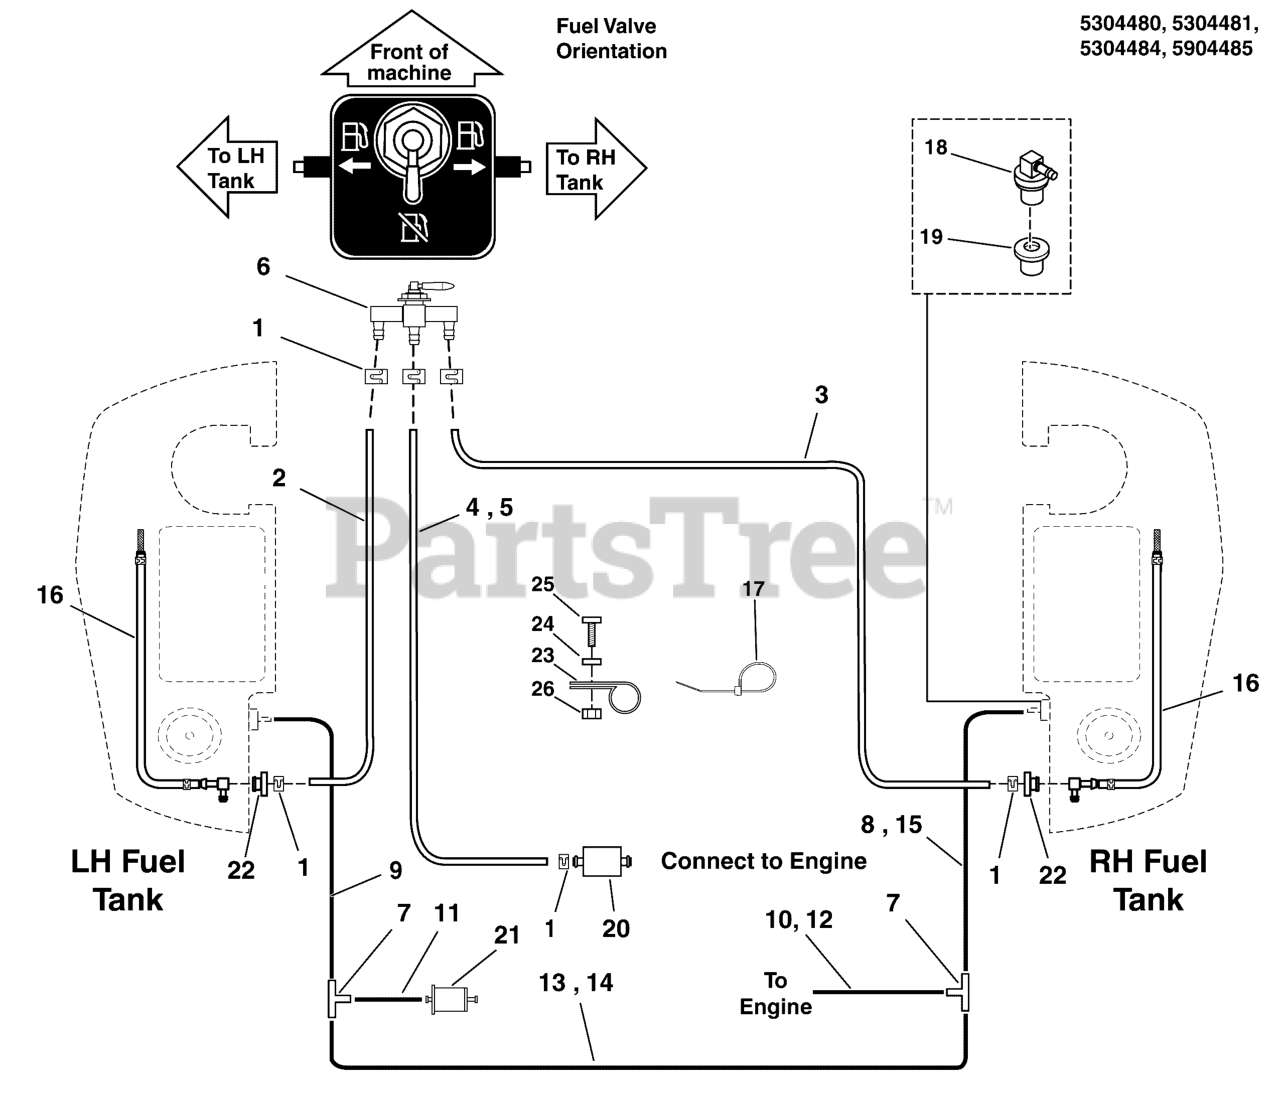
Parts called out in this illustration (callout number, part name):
1	CLAMP, HOSE, EXTERNAL, 1/2 - RED
2	HOSE, 1/4" FUEL, 14.50"
3	HOSE, 1/4" FUEL, 49.00"
4	HOSE, 1/4" FUEL, 22.00"
5	HOSE, 1/4" FUEL, 11.00"
6	VALVE, FUEL SHUT-OFF, 11772
7	FITTING, 3/16" TEE, BARB TYPE, HDPE
8	HOSE, VAPOR, 5MM ID, 41.00 LG
9	HOSE, VAPOR, 5MM ID, 26.00 LG
10	HOSE, VAPOR, 5MM ID, 31.50 LG
11	HOSE, VAPOR, 5MM ID, 2.00 LG
12	HOSE, VAPOR, 5MM ID, 11.00 LG
13	HOSE, VAPOR, 5MM ID, 2.00 LG
14	HOSE, VAPOR, 5MM ID, 13.50 LG
15	HOSE, VAPOR, 5MM ID, 28.00 LG
16	HOSE ASSEMBLY (SV)
17	TIE,SELF-LOCKING, 6"
18	REMOTE VENT ASSEMBLY
19	GROMMET (SV)
20	FUEL FILTER (SV)
21	FILTER, FUEL
22	BUSHING-FUEL TANK RED RUBBER
23	CLAMP, VINYL INSULATED, 1.00
24	WASHER, 1/4 SAE
25	BOLT, 1/4-20 X 3/4 GD5 CZ
26	NUT, 1/4-20 HEX SERR. FLANGE
